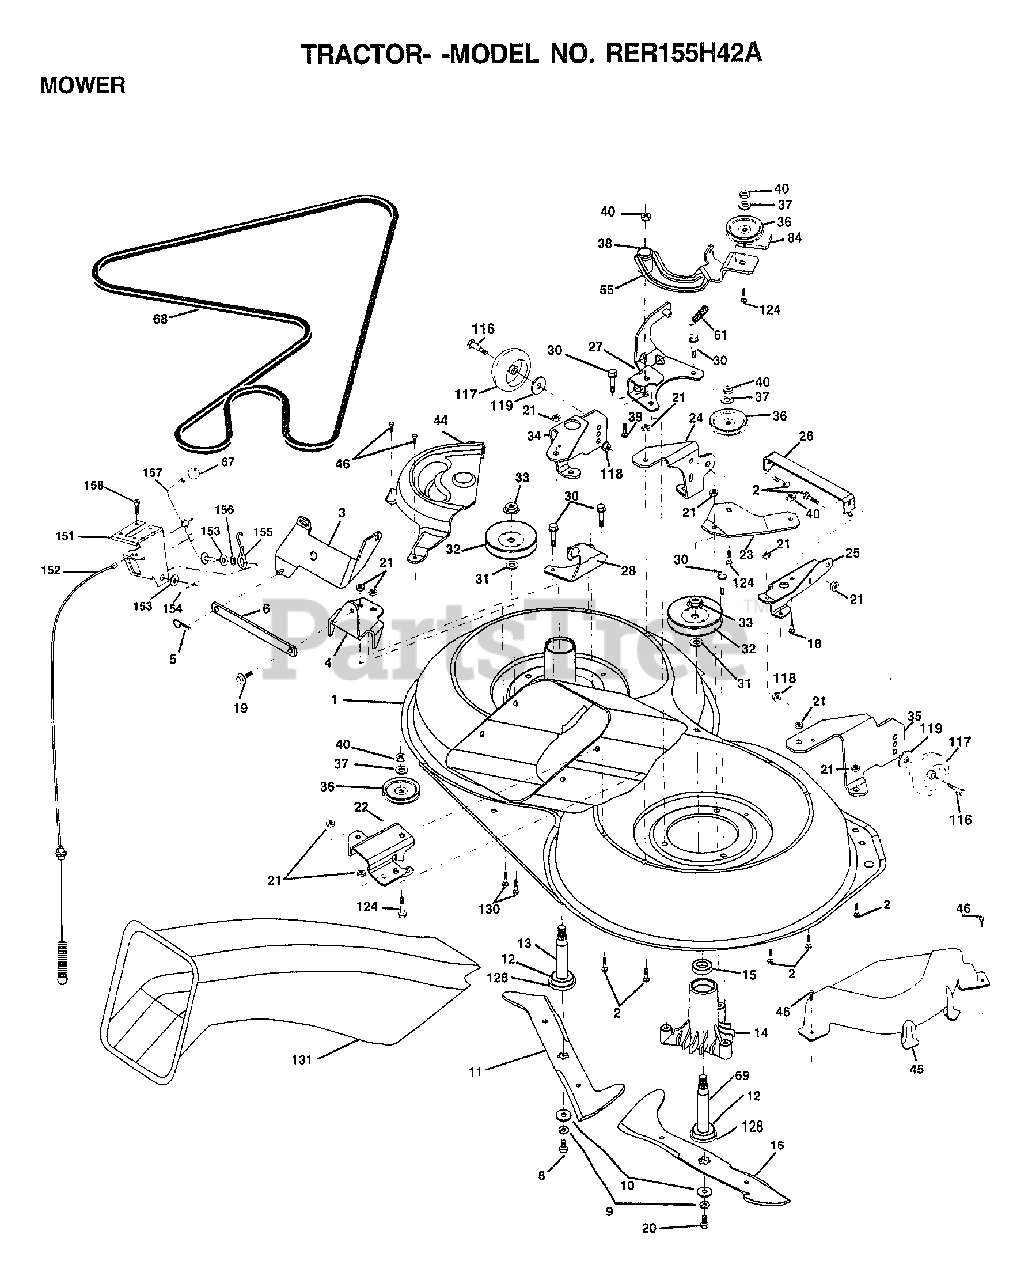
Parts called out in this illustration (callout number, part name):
1	HOUSING ASM MOWER
2	BOLT
3	BRKT.ASM.S-BAR.CHASSIS
4	BRKT BAR SWAY DECK
6	BAR.SWAY.92.CRD
8	BLADE BOLT
10	WASHER.HARD.BLADE
12	BEARING.BALL
14	HSG ASM MANDREL
15	BEARING
16	BLADE
18	BOLT D
19	BOLT SHD 5/16-18
20	BOLT.3/8-24X1.25
22	BRKT IDLER SPRT
23	BRKT IDLER SPRT
24	BRKT SUSPENSION
25	BRKT SUSPENSION
26	BRACE.SUPT.SUSP.FRT.CRD
27	BRKT ASM SUSP
28	BRKT ASM SUSP
30	"SCREW-THD ROLL,WA"
31	WASHER
32	PULLEY.MANDREL.42
34	BRKT GAUGE WHEEL
35	BRKT GAUGE WHEEL
36	PULLEY.IDLER.4.25
37	WASHER
38	SPACER HUB ARM IDLER
39	BOLT
44	COVER MANDREL
45	COVER MANDREL
46	SCREW.1/4-20X5/8
55	ARM IDLER
61	SPRING.TENSION.BELT
67	KNOB T(3/8 HOLE)
68	HEX-BELT
69	SHAFT.ASM.W/LWR.BRG.RH.THD
84	"KEEPER-BELT,IDLER"
116	BOLT.SHOULDER
117	WHEEL GAGE DONUT
118	LOCKNUT
119	WASHER
124	BOLT.3/8-16X1.50
128	WASHER.FELT.
131	CHUTE.BAGGER.CRD
151	BRKT CLUTCH CABLE
152	CABLE CLUTCH CRD SERVICE
153	WASHER FLAT
154	SPRING RETAINER
155	SPRING RETENTION LVR CLUTCH CAB
156	SPACER
157	ROD.CLUTCH.CABLE.3/8
158	SCREW LT
